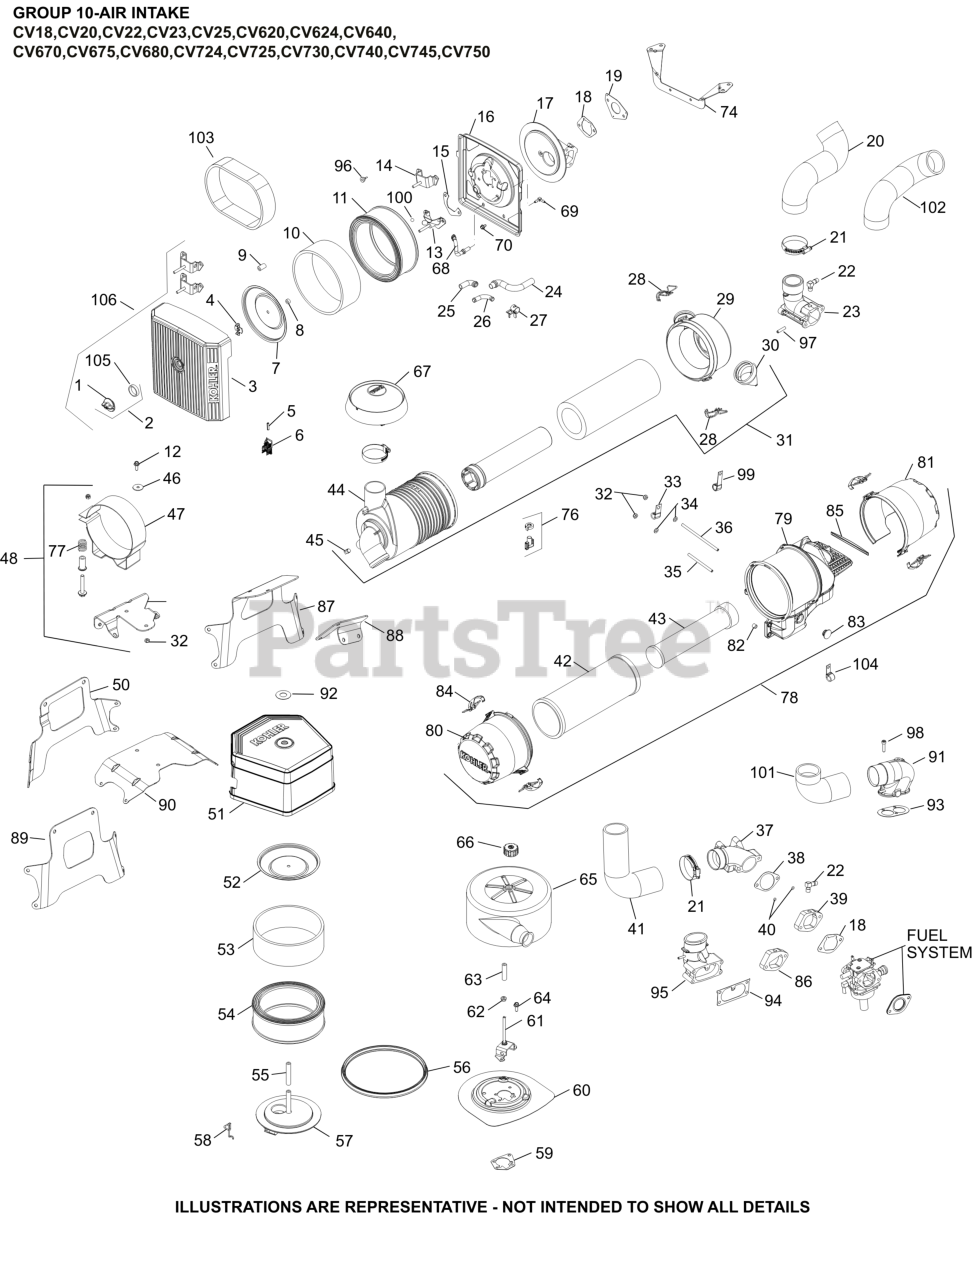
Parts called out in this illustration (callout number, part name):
42	ELEMENT, AIR FILTER - PRIMARY
43	ELEMENT, AIR FILTER - SAFETY
78	KIT, AIR CLEANER
80	COVER, AIR FILTER
81	COVER, RAIN CAP
83	PLUG, HOLE
84	CLIP ASSEMBLY
85	DAMPER, FOAM INSERT
94	GASKET, AIR CLEANER ELBOW
104	CLIP, CABLE (KM)
NI	SCREW, FLG M6X1.0X25
